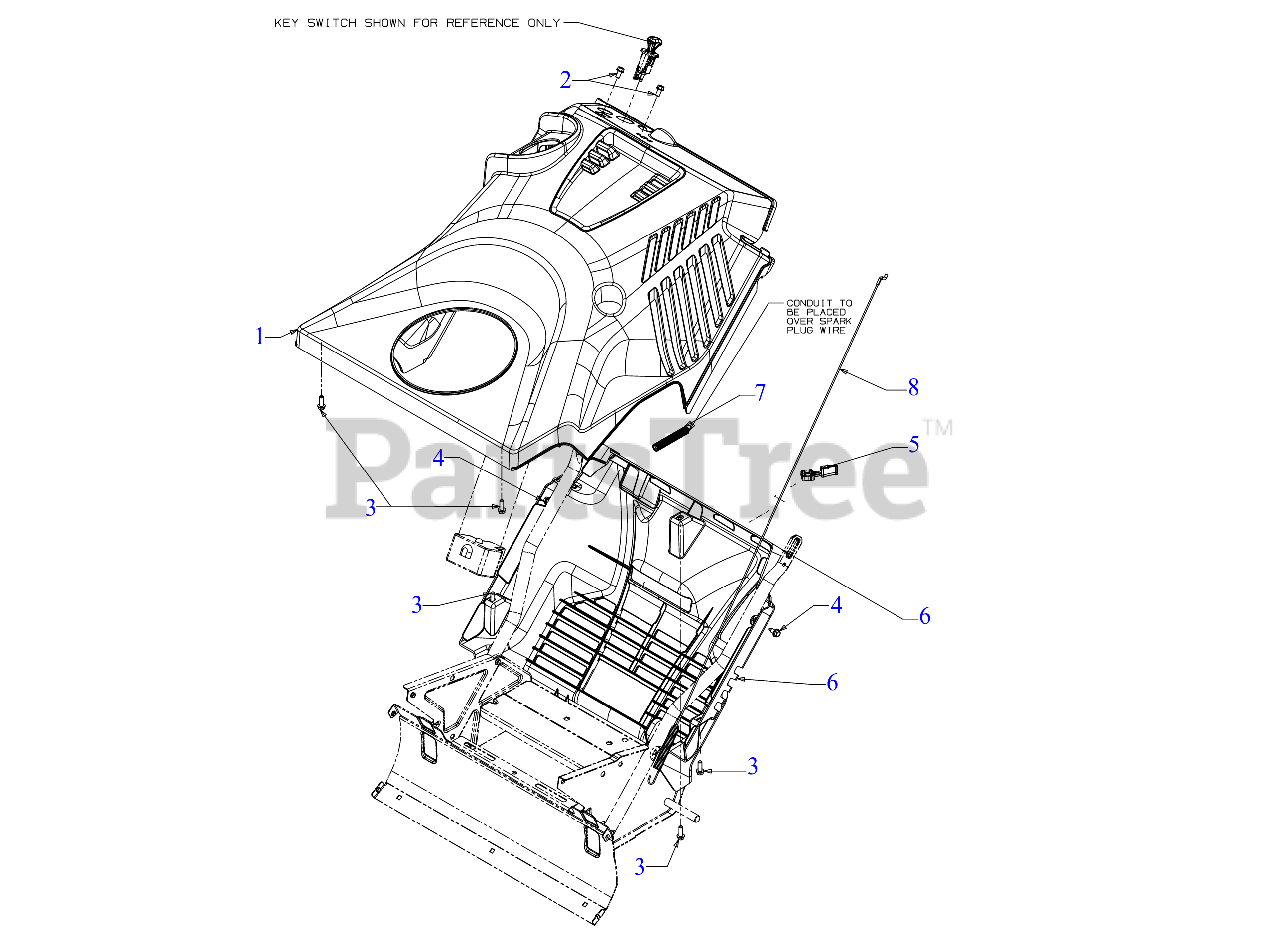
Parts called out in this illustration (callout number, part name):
1	COVER ASSEMBLY (CRAFTSMAN)
2	HEX SCREW 1/4-15 x .50
3	SCREW 1/4-15 x .750
4	SCREW 1/4-20X.625
5	CHOKE EXTENION LEVER
6	BOTTOM COVER
7	CONVOLUTED CONDUIT
8	AUGER CLUTCH CABLE 37.05"
